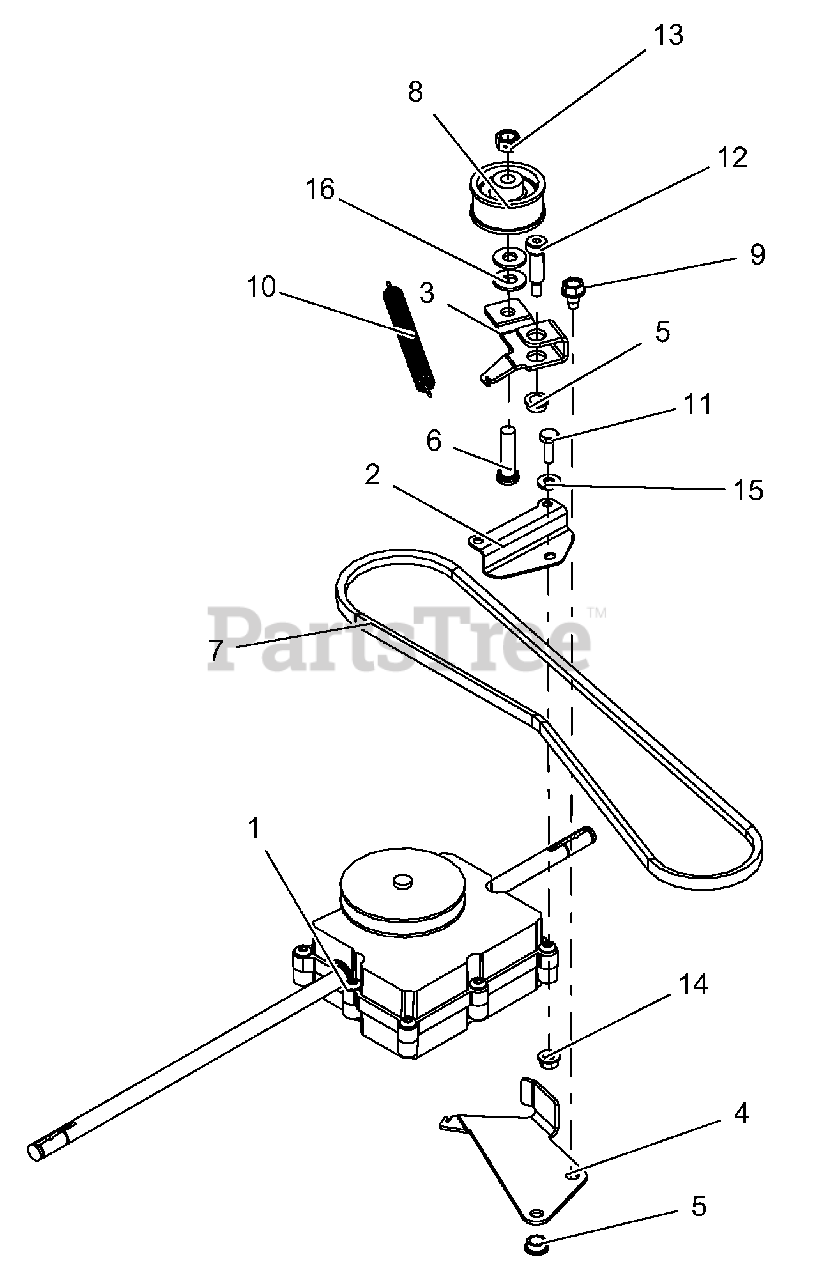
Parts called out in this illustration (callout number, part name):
1	TRANS, 21" MOWER, 3 SPD
2	BRKT, TRANS
3	ARM, IDLER
4	BRKT, IDLER
5	BSHG, IDLER ARM
6	BOLT, STUD
7	V-BELT, 3L SECTION
8	IDLER, FLAT 1.875 OD X .75 WIDE
9	SCR-TAP .31-18X.50 HWH TR YWZ
10	SPRG, EXTENSION
11	BLT-HEX .25-20X.75 GR5 YWZC
12	BLT-SHLDR .375X1.00X.25-20
13	NUT-LK-CTR .38-16 YWZC
14	NUT, LK-TOP-FLG .25-20 YWZC
15	WSHR-FL-STL.281X.62X.065 YWZC
16	WSHR-FL-STL.38X.875X.083 YWZC
